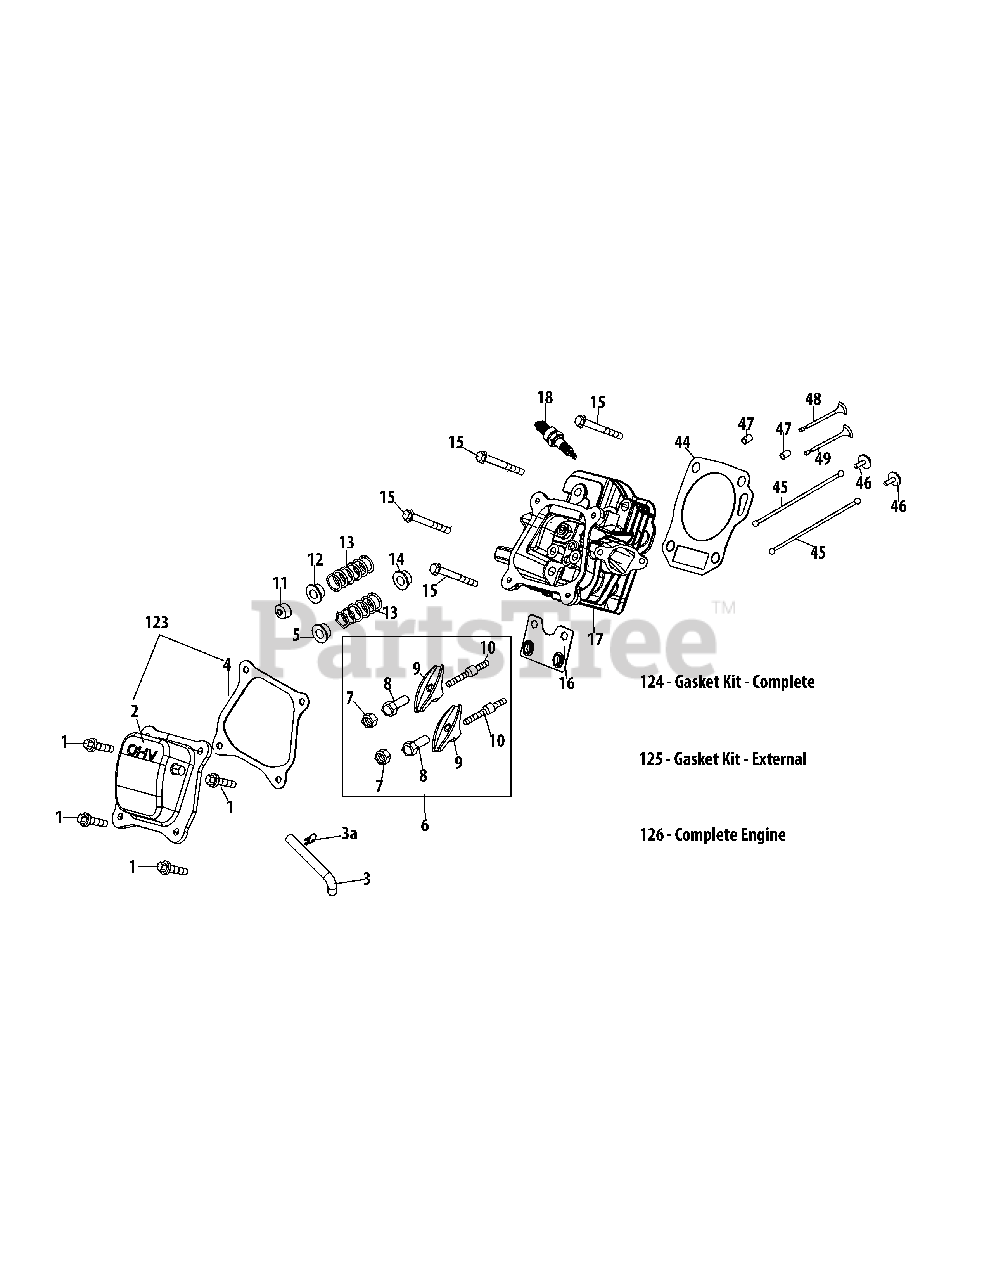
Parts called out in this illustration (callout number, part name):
1	Bolt M6×16
2	Valve Cover
3	Breather Hose
4	Valve Cover Gasket
5	Valve Spring Retainer (Intake)
6	Rocker Arm Assembly
7	Pivot Locking Nut
8	Adjusting Nut ,Valve
9	Rocker Arm
10	Pivot Bolt
11	Exhaust Lash Cap
12	Valve Spring Retainer (Exhaust)
13	Valve Spring
14	Valve Seal (Intake)
15	Bolt M8×55
16	Push Rod Guide
17	Cylinder Head Assembly
18	Spark Plug/F6Rtc
44	Cylinder Head Gasket
45	Push Rod Kit
46	Tappet
47	Dowel Pin 10X16
48	Valve Kit
49	Valve Kit
123	Valve Cover Kit
124	Gasket Kit-Complete
125	Gasket Kit-External
126	Complete Engine
